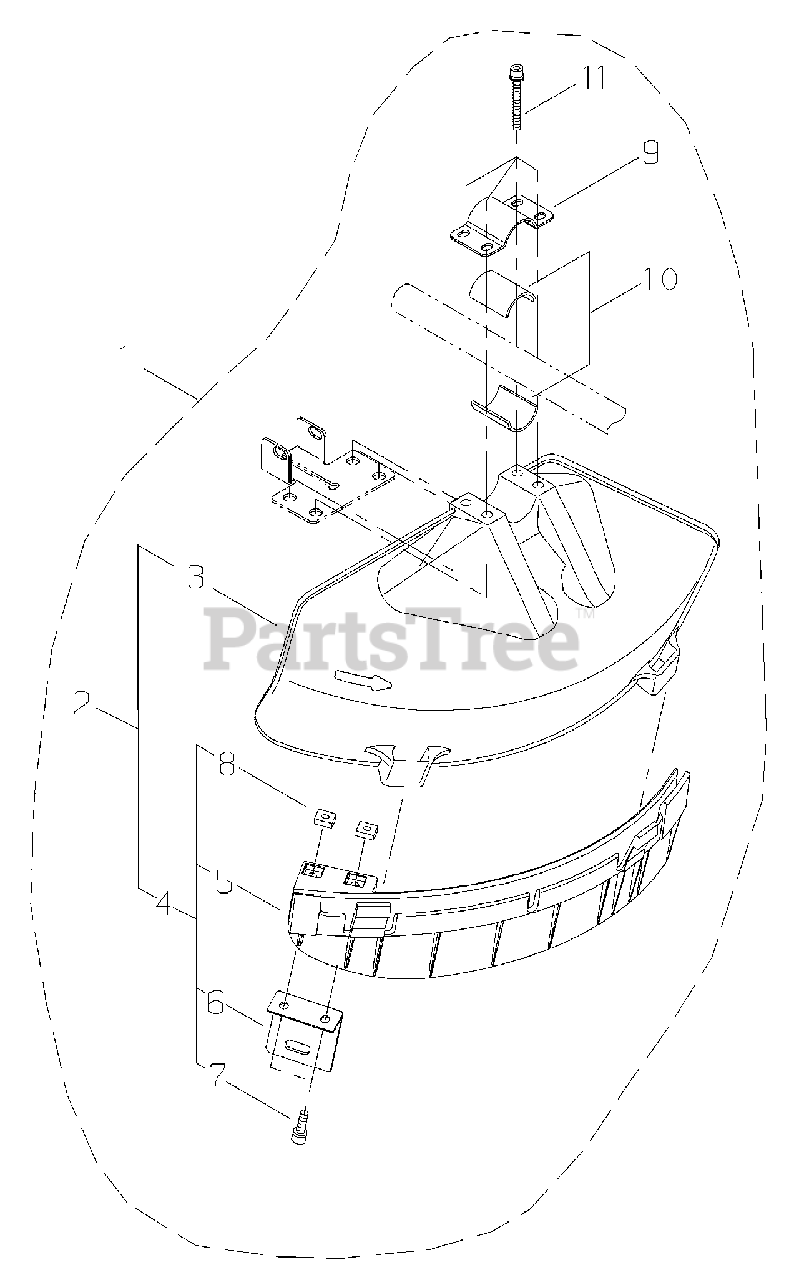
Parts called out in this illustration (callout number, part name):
1	GUARD SET
2	DEBRIS SHIELD ASSY
3	SHIELD, DEBRIS
4	SUB-SHIELD ASSY
5	SHIELD, DEBRIS
6	KNIFE, TRIMMER LINE
7	SCREW - 5X22
8	NUT - 5
9	CLAMP - UPPER
10	SPACER
11	SCREW - 5X45
